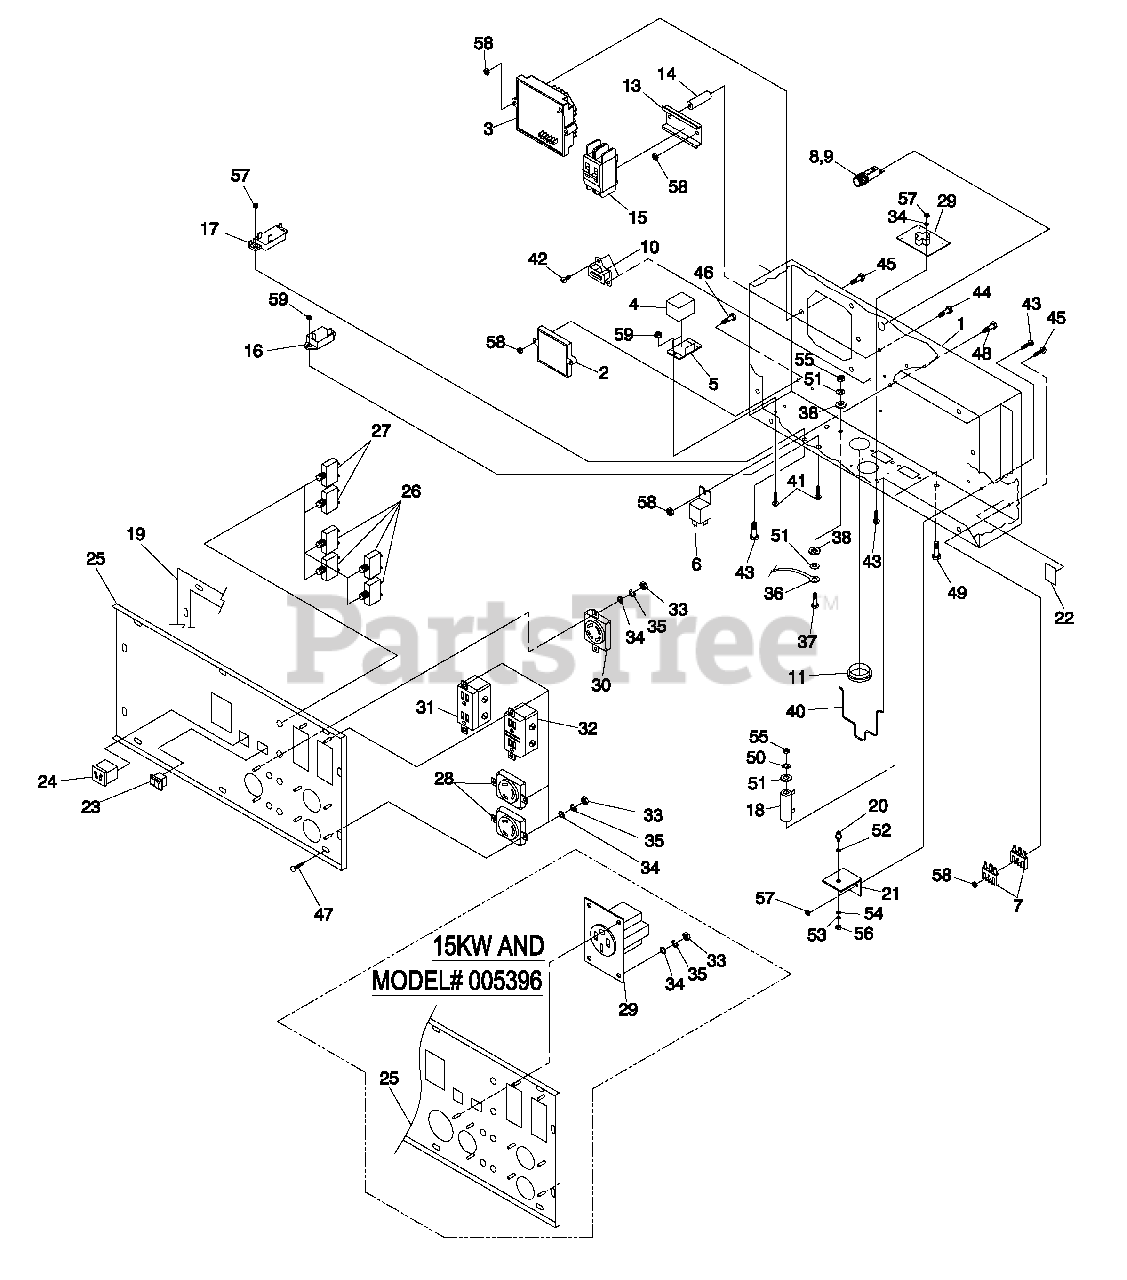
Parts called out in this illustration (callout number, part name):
1	CONTROL PANEL BOX (15 KW & 005396)
2	ELECTRONIC GOVERNOR / IDLE CONTROLLER
3	ASSY PCB VREG AIR COOLED
4	RELAY 3PDT 12VDC
5	RELAY BASE 3PDT 12VDC
6	RELAY PNL 12VDC SPST 30A
7	RECTIFIER-BATTERY CHARGER
8	HOLDER FUSE
9	FUSE 10A X AGC10
10	TRANSFORMER, IDLE CURRENT
11	BUSHING SNAP
13	DIN RAIL 59.5mm LONG
14	SPACER .25 X .50 X 2.5 (17.5 KW)
15	CIRCUIT BREAKER 50A 400V 2POLE
16	CIRCUIT BREAKER 10A 1POLE
17	CIRCUIT BREAKER 6A 1POLE
18	RESISTOR 25R 5% 25W
19	GASKET, PORTABLE CONTROL PANEL
20	RECTIFIER 1N1206R
21	HEATSINK
22	TAPE ELEC UL PERMACEL
23	SWITCH, ROCKER -/0
24	OUTLET, 12VDC SNAP
25	PANEL, SHEET METAL (15 KW & 005396)
26	CIRCUIT BREAKER 30A
27	CIRCUIT BREAKER 20A
28	OUTLET 30A 120V RECEPT
29	OUTLET 50A 125/250V
30	OUTLET 30A 125/250V
31	OUTLET 20A 120V DPLX
32	OUTLET 20A 120V GFCI
33	NUT HEX M4-0.7 (15 KW & 005396)
34	WASHER FLAT #8 (15 KW & 005396)
35	WASHER LOCK M4 (15 KW & 005396)
36	GROUND WIRE
37	SCREW HHC M6-1.0 X 35
38	WASHER LOCK SPECIAL 1/4"
40	SPRING RETAINER (17.5 KW)
41	SCREW PPHM M3-0.5 X 12
42	SCREW PPHM M3-0.5 X 8
43	SCREW PPHM M4-0.7 X 10
44	SCREW PPHM M5-0.8 X 80 (17.5 KW)
45	SCREW PPHM M5-0.8 X 30
46	SCREW HHC M5-0.8 X 25
47	SCREW HHTT M5-0.8 X 10
48	SCREW HHC M5-0.8 X 10
49	SCREW HHC M6-1.0 X 65
50	WASHER LOCK M6 (1/4")
51	WASHER FLAT 1/4"
52	WASHER MICA .203
53	WASHER FLAT #10
54	WASHER STEP NYLON .20
55	NUT HEX M6-1.0
56	NUT HEX #10-32
57	NUT HEX M4-0.5 NYINS
58	NUT HEX M5-0.8 NYINS
59	NUT HEX M3-0.5 NYINS
